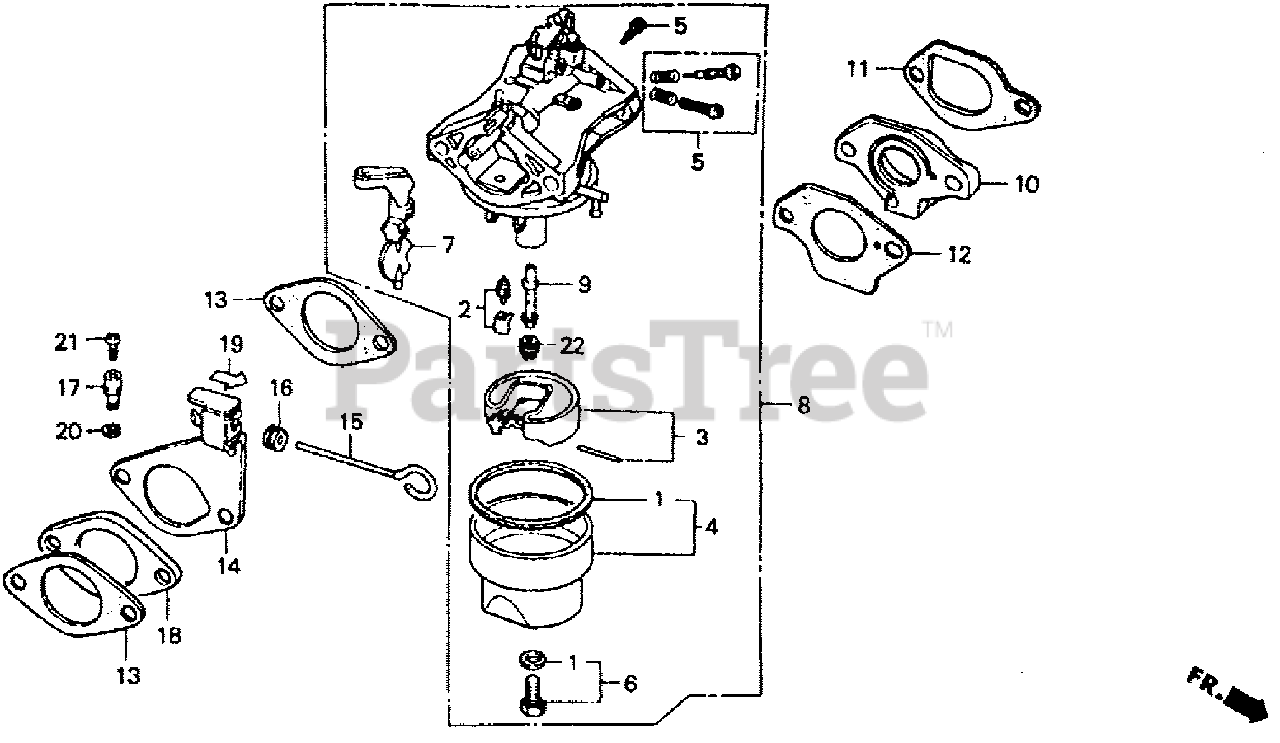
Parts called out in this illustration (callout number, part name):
1	GASKET SET
2	VALVE SET, FLOAT
3	FLOAT SET
4	CHAMBER SET, FLOAT
5	SCREW SET A
6	SCREW SET B
7	CHOKE SET
8	CARBURETOR ASSY.
8	CARBURETOR ASSY. (BB35D E)
9	NOZZLE, MAIN
10	INSULATOR, CARBURETOR
11	GASKET, INSULATOR
12	GASKET, CARBURETOR
13	GASKET, AIR CLEANER
14	STAY, CHOKE CONTROL
15	ROD, CHOKE CONTROL
16	GROMMET, CHOKE ROD
17	HOLDER, CABLE
18	SPACER, AIR CLEANER
19	MARK, CHOKE
20	CIRCLIP (5MM)
21	SCREW, PAN (4X8)
22	JET, MAIN (#88)
22	JET, MAIN (#90)
22	JET, MAIN (#92)
22	JET, MAIN (#95)
22	JET, MAIN (#98)
22	JET, MAIN (#100)
22	JET, MAIN (#102)
